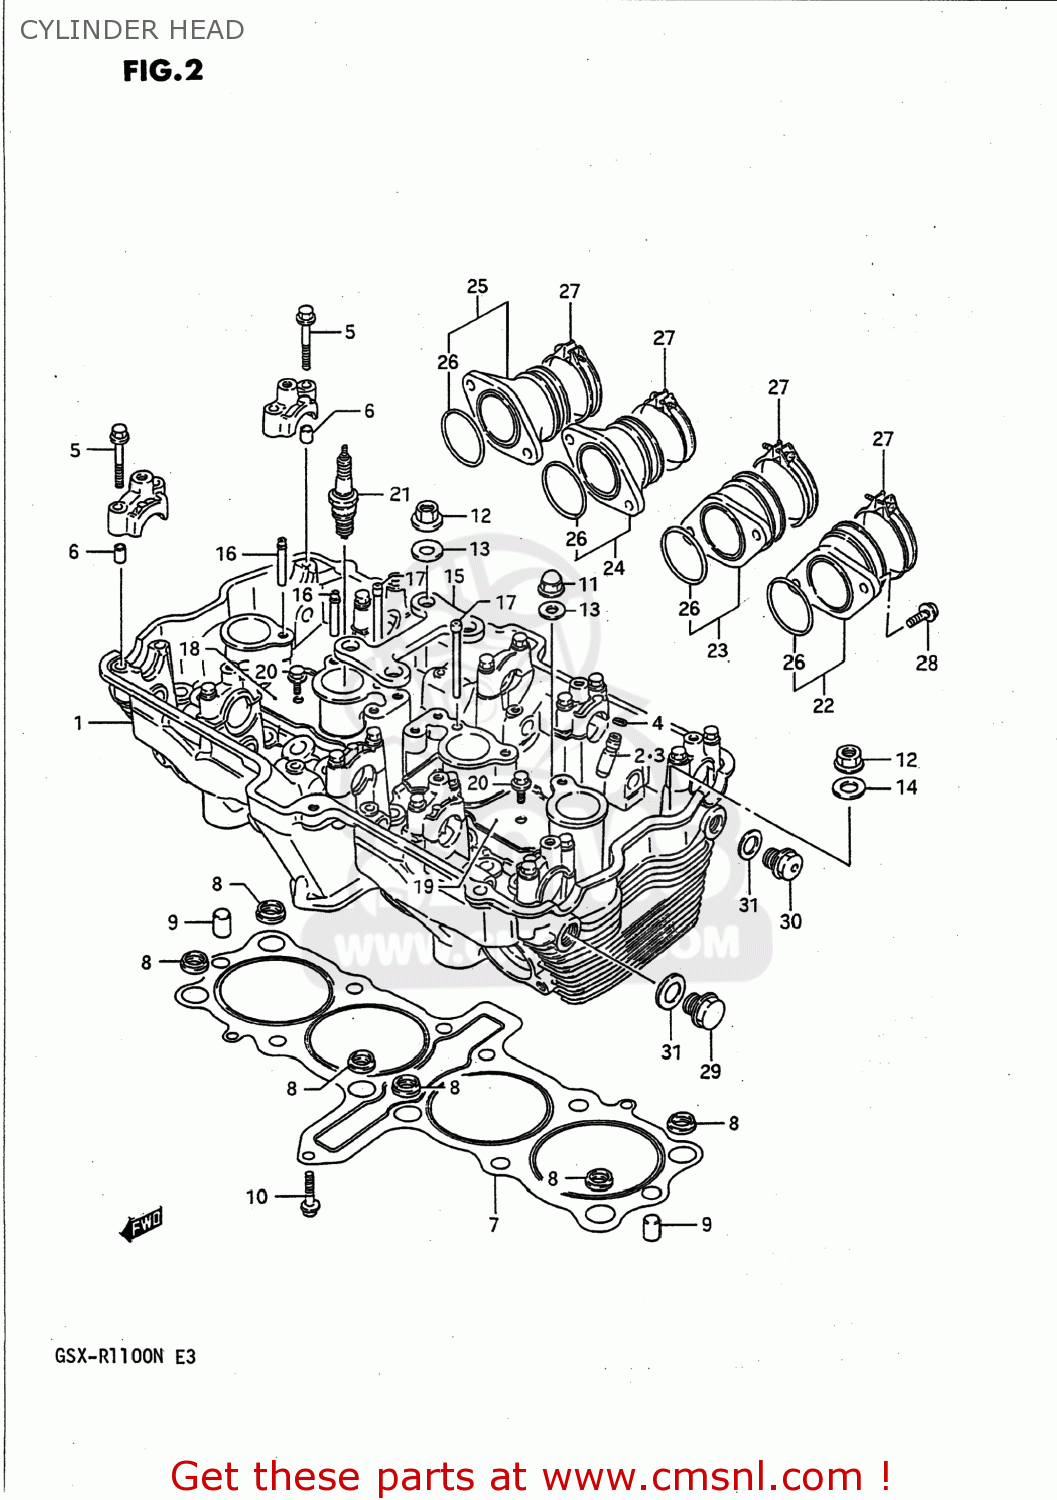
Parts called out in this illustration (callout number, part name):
1	HEAD ASSEMBLY,CYLINDER
2	GUIDE,VALVE
3	GUIDE,VALVE
4	RING,SNAP
5	BOLT(6X39)
6	PIN(6.2X8X11)
7	GASKET,CYLINDER HEAD (NAS)
8	O-RING,HEAD GASKET
9	PIN
10	BOLT
11	NUT
12	NUT
13	GASKET(10.2X20X2).3 (NAS)
14	WASHER (10.5X22X2.3)
15	PLATE,HEAD REINFORCEMENT
16	PIPE,OIL NO.1
17	PIPE,OIL NO.3
18	PLATE,OIL PIPE,R
19	PLATE,OIL PIPE,L
20	BOLT
21	PLUG,SPARK(JR9B)
22	PIPE,INTAKE NO.1
23	PIPE,INTAKE NO.2
24	PIPE,INTAKE NO.3
25	PIPE,INTAKE NO.4
26	O RING(D:2.4,ID:39.7)
27	CLAMP
28	SCREW
29	PLUG
30	PLUG
31	GASKET(14X19.2X2) (NAS)
